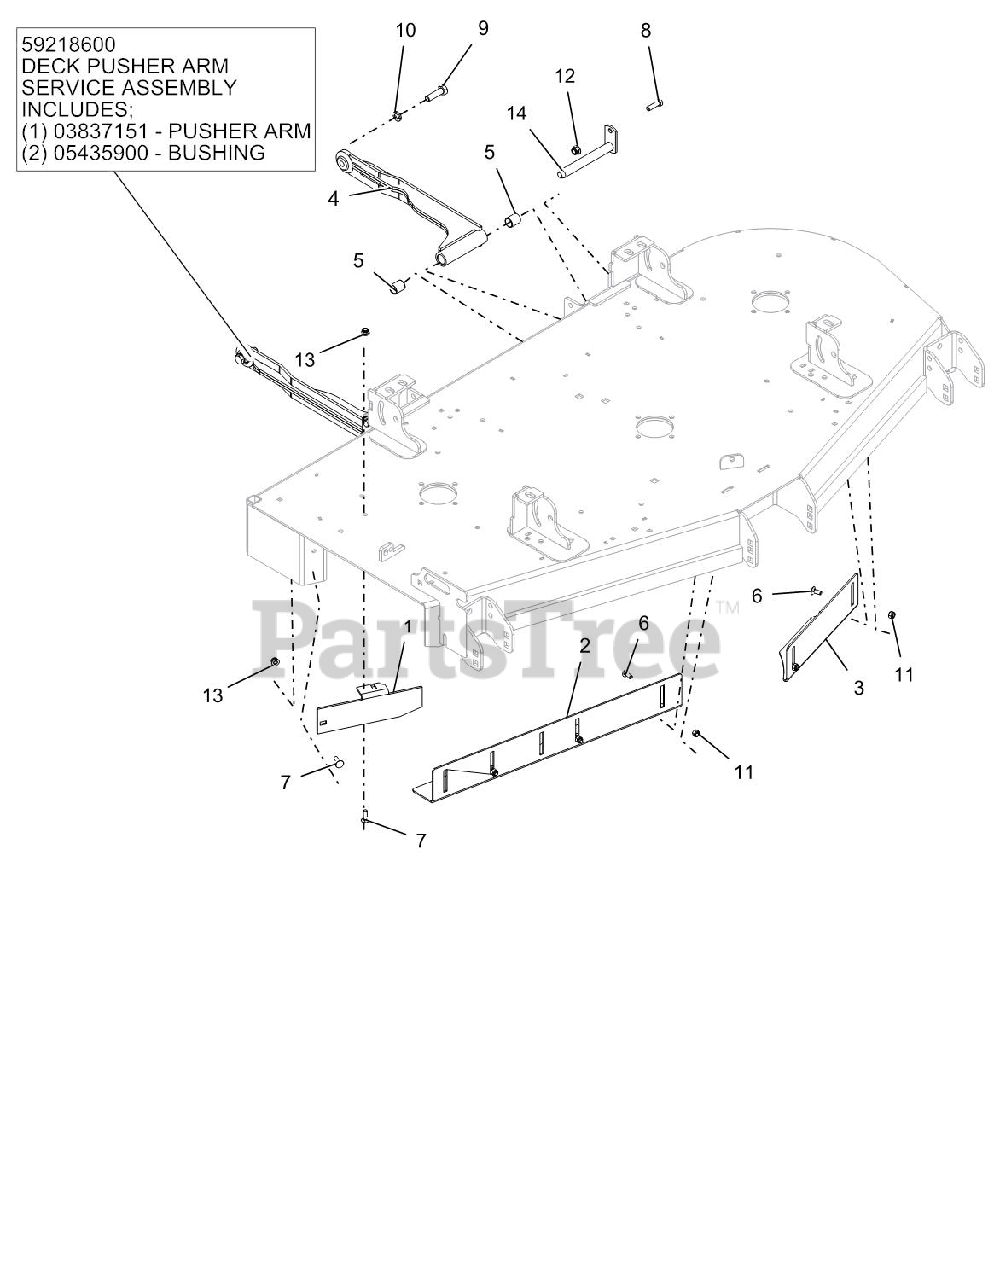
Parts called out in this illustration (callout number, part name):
1	BAFFLE, 60" DISCHARGE
2	BAFFLE, 60" RH VACUUM
3	BAFFLE, 60" LH VACUUM
4	WLDMT, DECK STABILIZER ARM
4	DECK PUSHER ARM SERVICE ASSEMBLY
4	PUSHER ARM
4	BUSHING
5	BRG, .750 X .875 X 1.000
6	BLT-RDHDSQNK .31-18X.75 G5 YWZC
7	BLT-RDHDSQSHNK .31-18X1.00 G5 Y
8	BLT-HEX .38-16X1.25 GR5 YWZC
9	BLT-HEX .50-13X1.75 GR5 YWZC EP80
10	WSHR-LK .50X.125 REG YWZC
11	NUT-LK-NYL .312-18 YWZC
12	NUT-LK-NYL-FLG .38-16 YWZC
13	NUT-LK-NYL-FLG .31-18 YWZC
14	WLDMT, MOWER MTG. PIN
